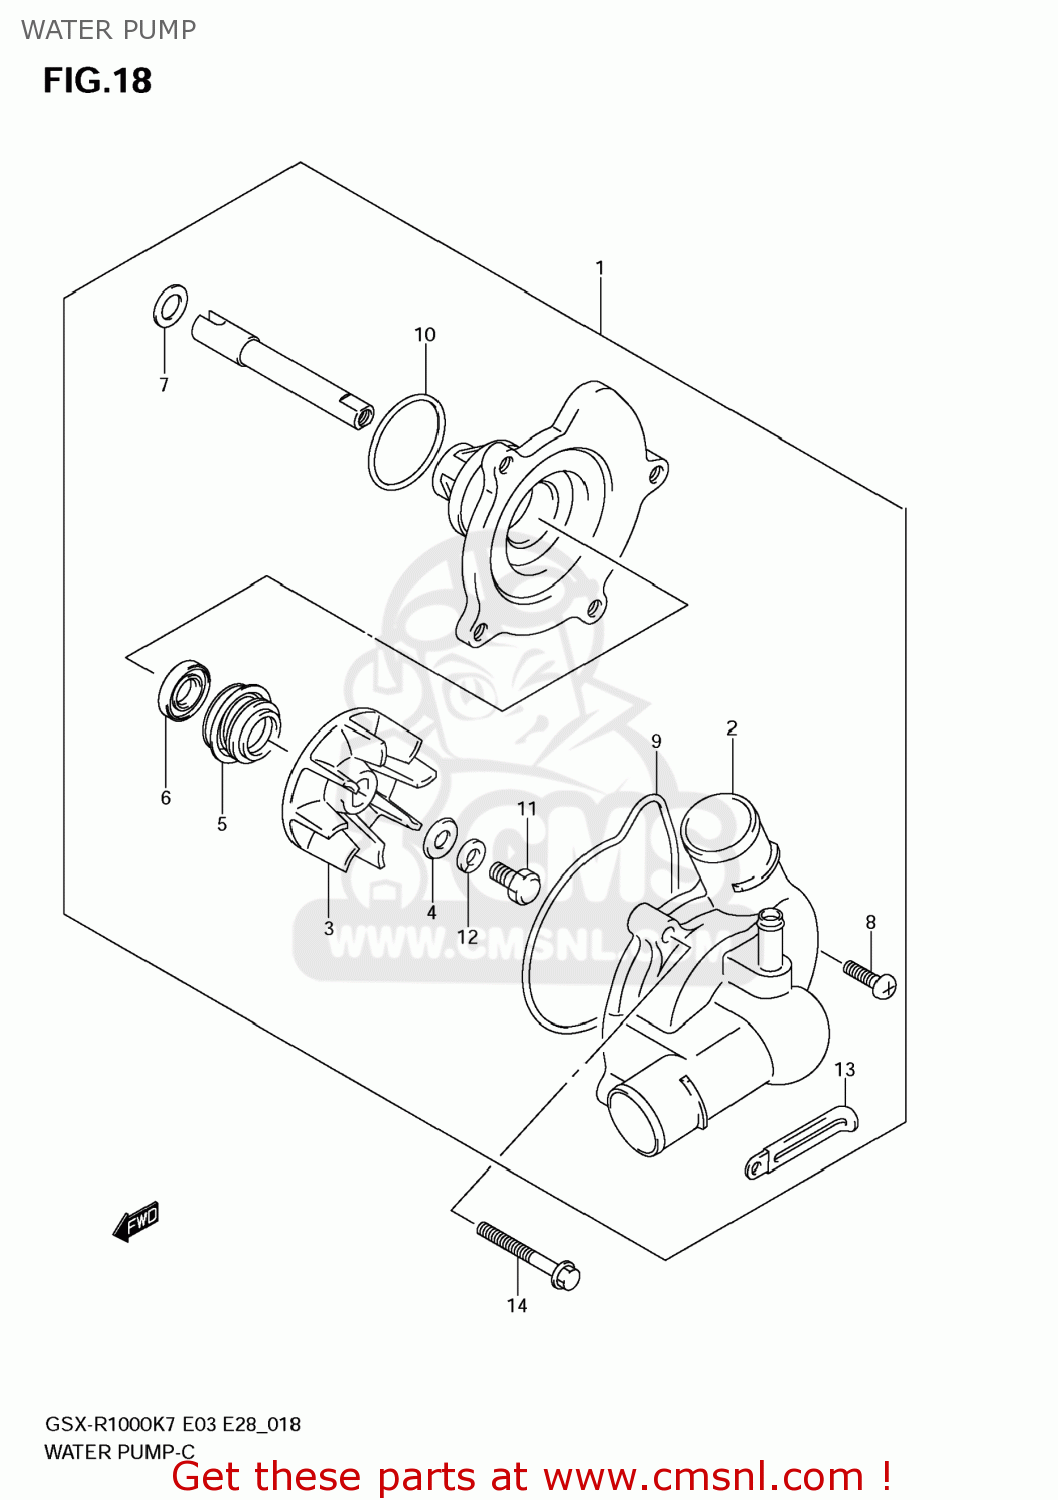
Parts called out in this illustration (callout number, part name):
1	PUMP ASSY,WATER
2	CASE,WATER PUMP
3	IMPELLER
4	GASKET(6X15X2.2) (NAS)
5	SEAL,MECHANICAL
6	SEAL,OIL
7	WASHER
8	SCREW
9	O RING
10	O RING,WATER PUMP HOLDER
11	BOLT(6X13)
12	WASHER
13	CLAMP(L:45)
14	BOLT
